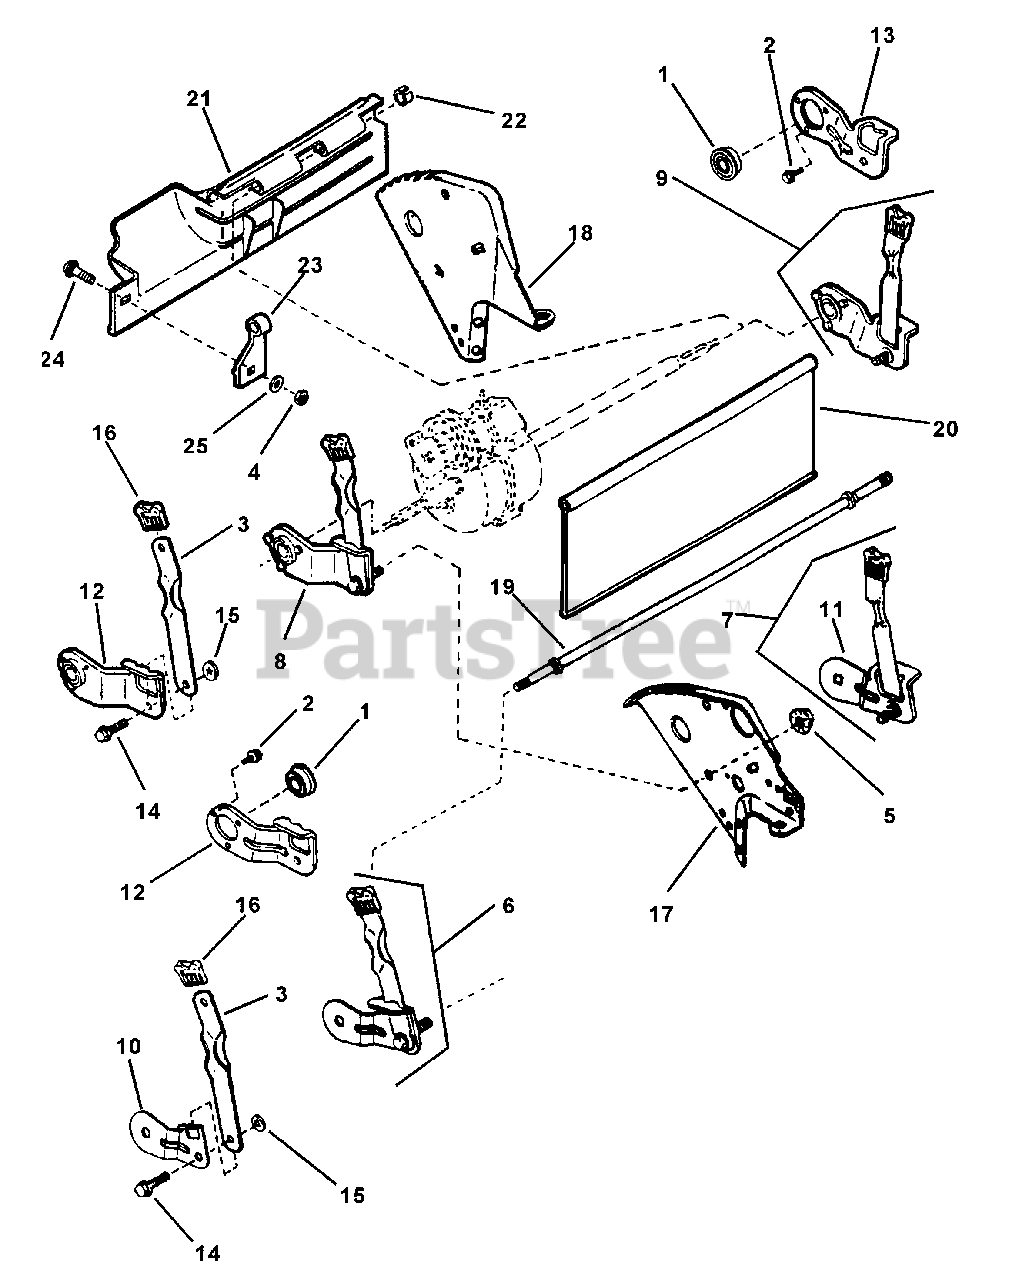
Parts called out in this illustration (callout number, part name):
1	BEARING, 9/16
2	SCREW, #10-32 x 3/8" Self-Tapping (Torx)
3	LATCH, Height Adjusting (Long)
4	NUT, 1/4-20 Hex, Grade 5
5	NUT, 5/16-18 Hex Flange Lock, Grade 5
6	ASSEMBLY, Wheel Arm (Right Rear)
7	ASSEMBLY, Wheel Arm (Left Rear)
8	ASSEMBLY, Wheel Arm (Right Rear)
9	ASSEMBLY, Wheel Arm (Left Rear)
10	ARM, Round Axle End (Round Opening) (Right Rear)
11	ARM, Square Axle End (Square Opening) (Left Rear)
12	ARM, Wheel Right Rear
13	ARM, Wheel Left Rear
14	BOLT, 5/16-18 x 1" Shoulder
15	RETAINER, 5/16 Bolt
16	GRIP, Latch
17	BRACKET, Right Rear Wheel
18	BRACKET, Left Rear Wheel
19	AXLE
20	GUARD, Rear Foot
21	GUARD, Rear Foot
22	RING
23	SUPPORT, Foot Guard
24	BOLT, 1/4-20 x 1/2" Short Neck Carriage, Grade 5
25	WASHER, 1/4 Internal Tooth Lock
